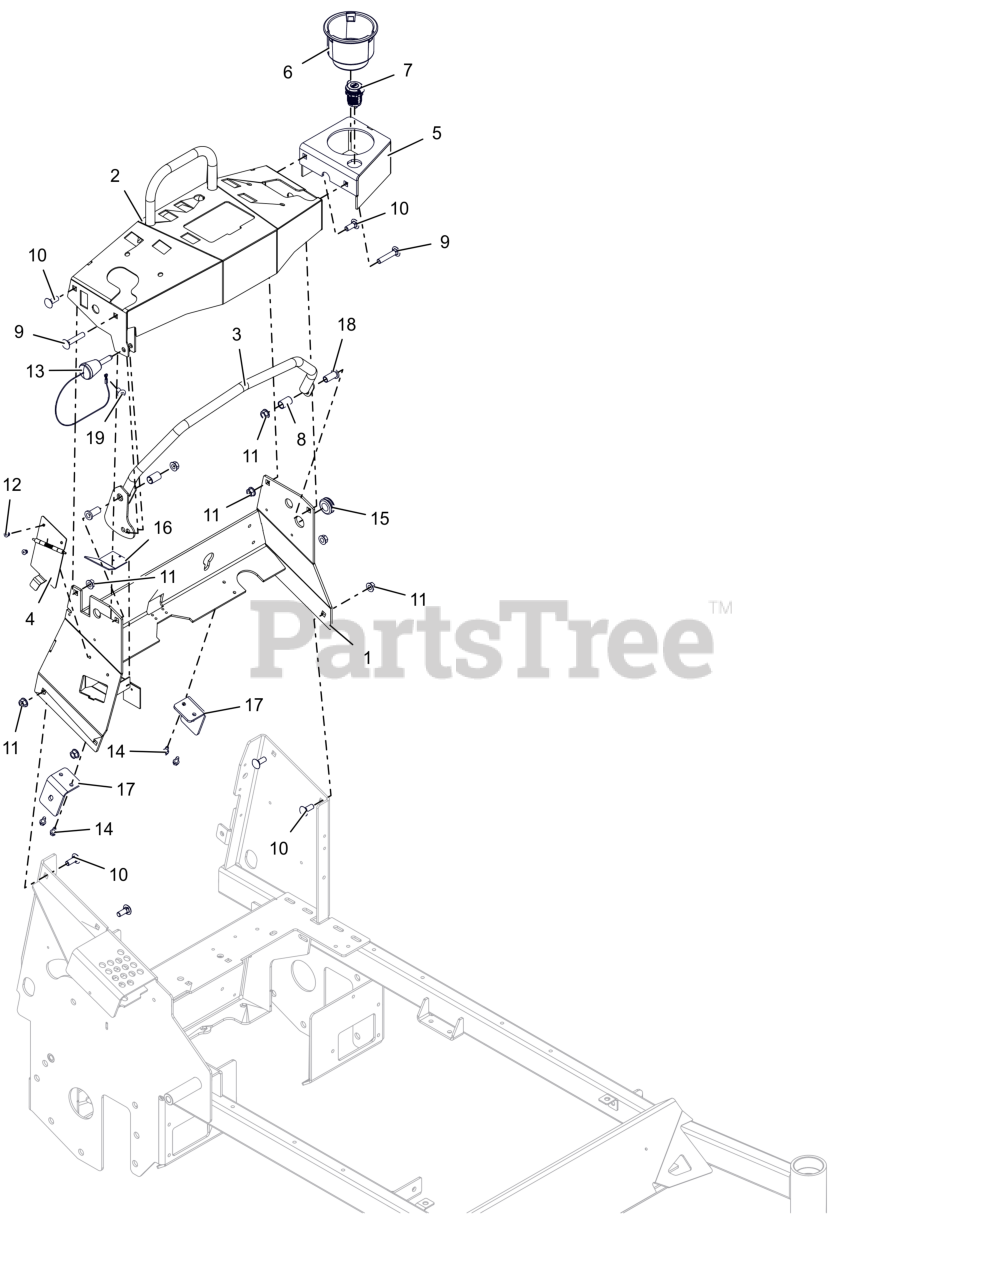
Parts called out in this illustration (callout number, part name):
1	WLDMT- TOWER
2	KIT- PSEV DASH
3	WLDMT- CRUISE BAR
4	ASM, CHARGER COVER
5	WLDMT, CUP HOLDER (RED)
6	CUPHOLDER, SNAP-IN 3.75OD
7	USB, DUAL PORT USB-C, 12V BLK
8	BRG, .500 x .625 x1.000
9	BLT, RHSN .38-16X2.00 G5 ZCC
10	BLT, RHSN .38-16X1.00 G5 ZCC
11	NUT-LK-CTR-FLG .375-16 GF ZCC
12	RVT, POP .187x.250 MULTIGRIP AL
13	PIN- MAGNETIC .375 X 1.5
14	SCR-TAP .25-20X.50 HWH ZCC
15	GROMMET,RUBBER.688 IDX1.000 OD
16	COVER- CHARGER BRACKET
17	BRKT- DAMPER MTG
18	BSHG, FLANGED
19	XMAS TREE FASTNER-BLACK
